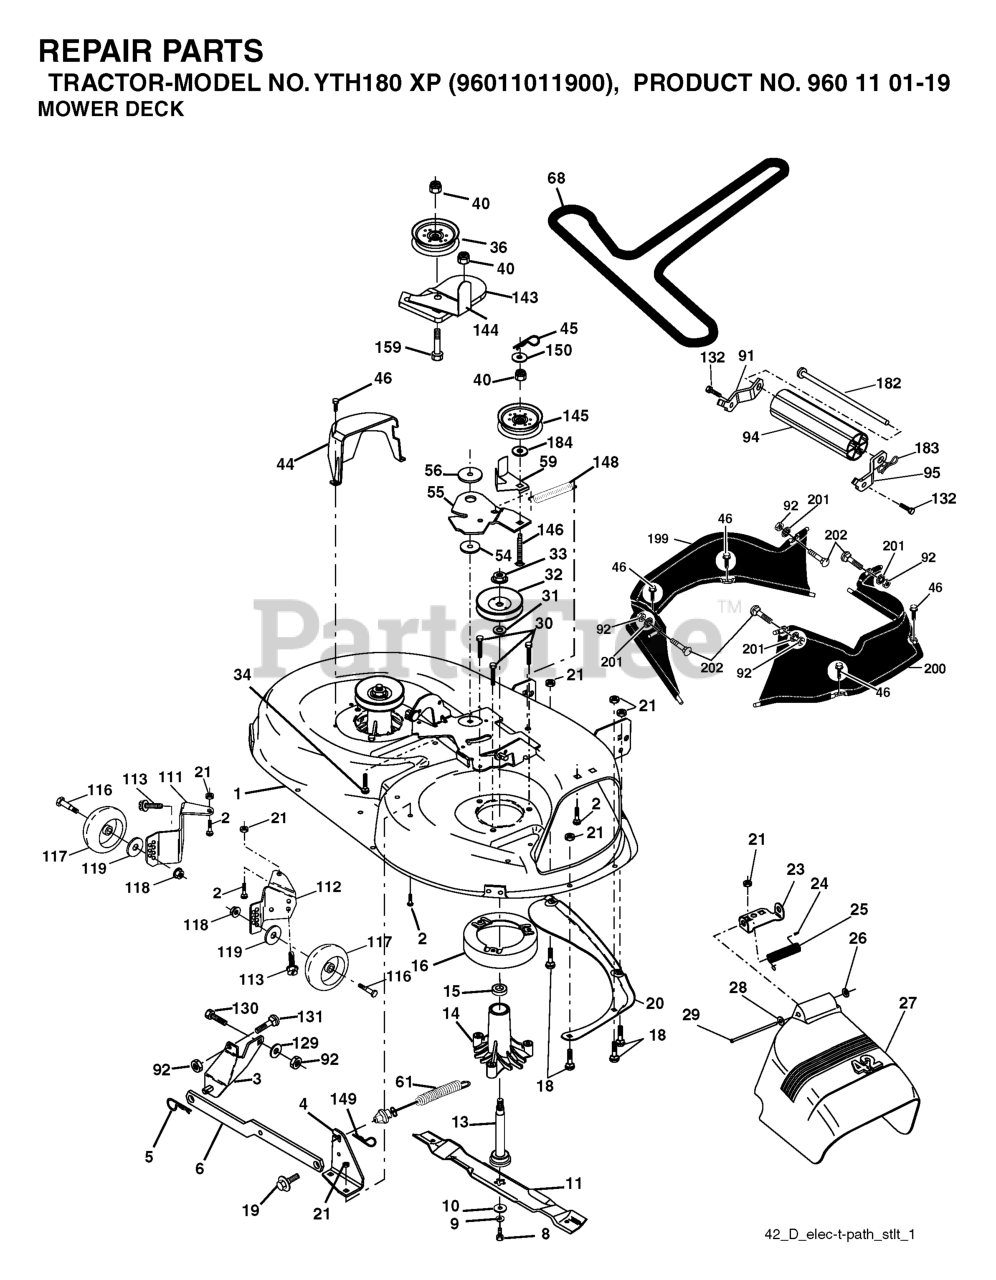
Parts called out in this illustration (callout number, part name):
1	42" DECK KIT
2	RP BOLT 5/16-18 X3/4 ZN/YEL GR
3	BRKT ASM SWAY BAR
4	BRACKET SWAY BAR 42" DECK
5	RETAINER-SPRNG RB
6	BAR SWAY DECK
8	BLADE BOLT
9	LOCKWASHER
10	WASHER.BLADE
11	42" HI-LIFT BLADE
13	SHAFT ASM VENT
14	RP.HOUSING.MANDREL.4PT.
16	STRIPPER.MANDREL.ROUND.BLACK
18	BOLT
19	BOLT SHD 5/16-18
20	BAFFLE.VORTEX
21	LOCKNUT
23	BRKT, DEFL. MOWER
24	CAP-SLEEVE LT
25	SPRING TORSION
26	NUT PUSH M
27	SHIELD ASM.DFLCTR MOWER 42"BLK
28	Washer 11/32 x 5/8 x 16 Ga SD
29	ROD.HINGE
30	SCREW, WASHER HEAD
31	WASHER.SPACER.MANDREL
32	PULLEY/MANDREL
33	NUT.FLANGE.LOCK.TOP
34	BOLT.3/8-16X1.50
36	FLAT IDLER PULLEY
40	NUT LOCK FLG 3/8-16 UNC
44	GUARD MANDREL LH BLACK
45	RETAINER M
46	SCREW.1/4-20X5/8
55	ARM IDLER 42" MOWER LT/YT
56	SPACER.RETAINER.MOWER
59	GUARD, BELT
61	SPRING EXT ELEC CLUTCH
91	BRACKET ASM NOSEROLLER LH
92	NUT
94	NOSE ROLLER
95	BRACKET ASM NOSEROLLER RH
111	BRACKET, WHEEL
112	BRACKET, WHEEL
113	BOLT.5/16HEX.WHS.HD
116	BOLT M
117	WHEEL.GAGE.HALF.SPOKED
118	LOCKNUT
119	WASHER.5/16.FLAT.STE.STD.
129	WASHER
131	BOLT D
132	SCREW, 3/8-16X3/4
143	BRACKET, ARM IDLER
144	DNO KEEPER.BELT.42".CLUTCH.CBL
145	PULLEY
146	BOLT, CARRIAGE IDLER BLACK
148	IDLER RETURN SPRING
149	SPRING.RETAINER.YELLOW.ZINC
182	ROD ROLLER NOSE STANDARD
183	PIN.COTTER.7/16.BOW TI.
184	WASHER
201	PUSH.NUT.ROUND.3/8.DIAM
202	BOLT D
